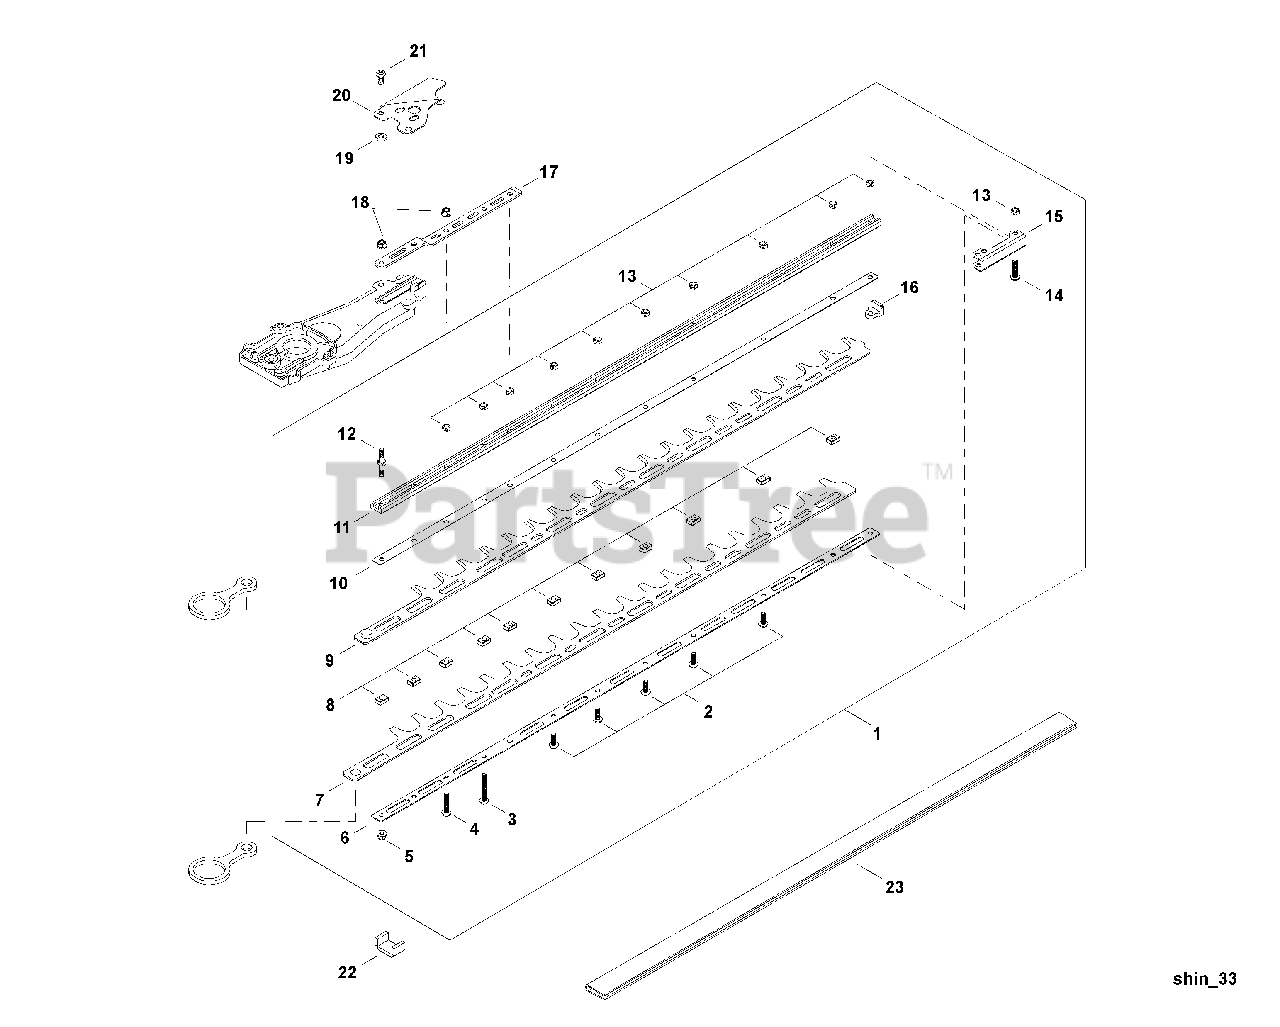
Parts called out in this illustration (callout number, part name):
1	CUTTER ASSY, 30"
2	BOLT M5×14
3	BOLT M5×35
4	BOLT M5×25
6	PLATE, LOWER
7	BLADE, LOWER 30"
9	BLADE, UPPER 30"
10	PLATE, UPPER
11	GUIDE BAR, 30"
12	STUD, MOUNTING M5
13	NUT, LOCK M5
14	BOLT M5×22
15	PLATE, GUIDE
17	BRACKET, CUTTER
19	WASHER M5
20	PROTECTOR
21	BOLT M6×12
22	PACKING, FELT
23	SCABBARD 30"
